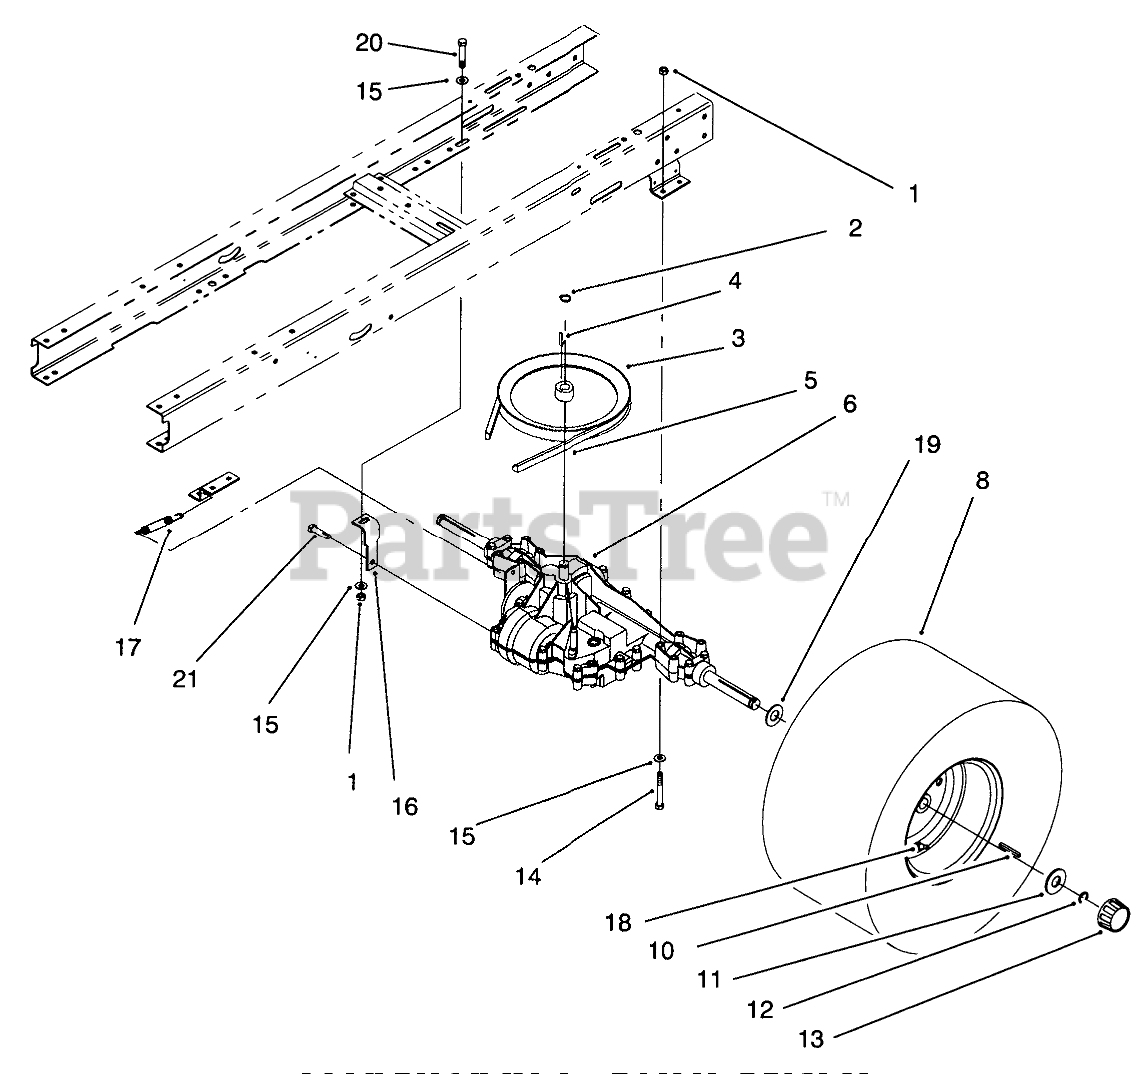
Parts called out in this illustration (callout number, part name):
1	NUT-LOCK, NI
2	RING-SNAP, EXTERNAL
3	PULLEY-TRANSMISSION
4	KEY-WOODRUFF
5	V BELT-TRACTION
6	TRANSAXLE ASM
7	FITTING-LUBE, 45 DEG
8	TIRE 16 X 6.50 X 8
9	RIM ASM
10	KEY-SQUARE
11	WASHER-PLAIN
12	E-RING
13	CAP-HUB
14	SCREW-HH
15	WASHER-PLAIN
16	STRAP-TORQUE
17	SPRING-RETURN, BRAKE
18	STEM-VALVE
19	WASHER-THRUST
20	SCREW-HH
21	SCREW-HWHTF
